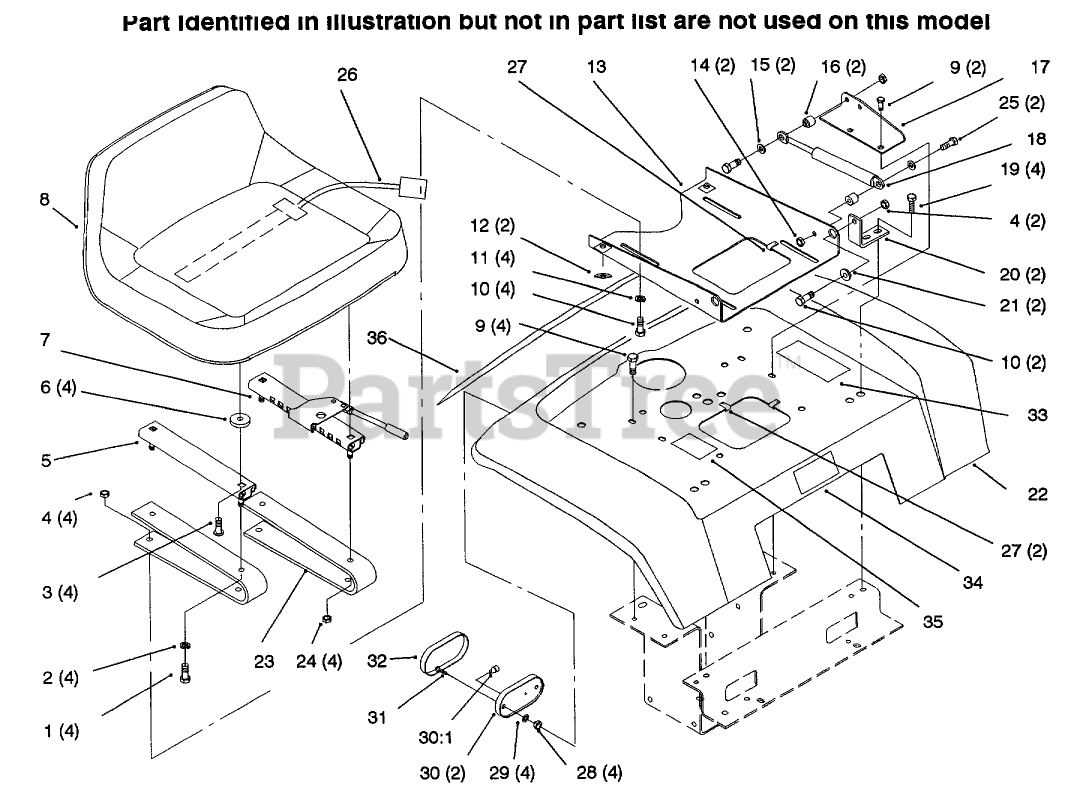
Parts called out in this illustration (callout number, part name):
3	Screw
4	NUT-LOCK, NI
5	ADJUSTER-R.H. SEAT
6	SPACER-NYLON
7	Adjuster-Seat
8	SEAT
9	Bolt
10	SCREW-HH
11	WASHER-PLAIN
12	BUMPER SJ5514 BLACK
13	Plate-SeatPivot
14	NUT-LOCK, NI
15	WASHER-FLAT
16	SPACER
17	BRACKET-CYLINDER R
18	GAS SPRING
19	SCREW-HWHTF
20	BRACKET-PIVOT
21	BUSHING
23	Seat Spring
24	NUT-LOCK, NI
25	SCREW-HH
26	SWITCH-SEAT
27	SPEED CLIP
28	NUT-LOCK, NI
29	WASHER-LOCK, INT
30	BASE-TAIL LIGHT
30:1	LIGHT BULB
31	SCREW-PPH
32	LENS-TAIL LIGHT
34	DECAL - WHEELHORSE
36	Decal-Rear Fender
